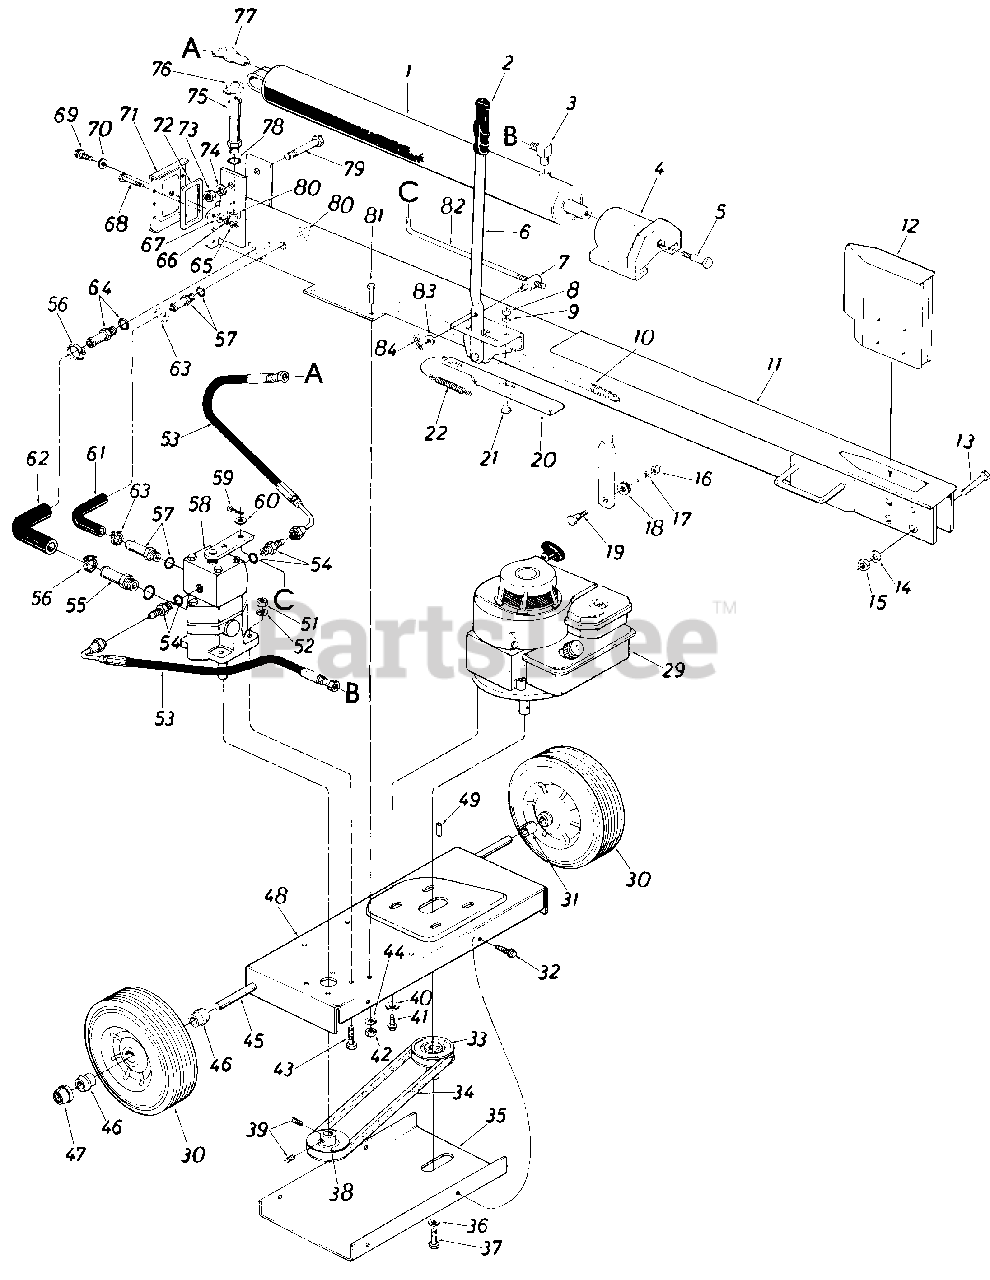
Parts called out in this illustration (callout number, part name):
1	2-1/2" Cylinder Ass'y. Comp.
2	Grip
3	90ø Elbow Adapter
4	Pusher Plate
5	Shoulder Bolt 5/8" Dia. x.660" Lg. 1/2-13 Thd.
6	Engagement Handle
7	Adjustment Ferrule
8	Hex Nut 5/16-18 Thd.
9	L.-Wash. 5/16" I.D.
10	Strainer Tube Ass y.
11	Oil Tank Ass'y. Comp
12	Wedge Ass y.
13	Hex Bolt 5/8-18 x 3.50" Lg. (Grade 5)
14	L.-Wash. 5/8" I.D.
15	Hex Nut 5/8-18 Thd.
16	Hex Nut 3/8-16 Thd.
17	L.-Wash. 3/8" I.D.
18	Rubber Wash.
19	Shoulder Bolt .498x .340
20	Engagement Brkt.
21	Shoulder Bolt .437" Dia. x.180" Lg.
22	Extension Spring .50" O.D. x 4. 25" Lg.
29	Engine-B & S
30	Wheel Ass'y. Comp. 10.0" x 2.75
31	Sleev .532" I.D. x 875" O.D. x .90" Lg.
32	Hex Wash. Hd. Self Tap. Scr. 1/4-20 x .50" Lg.
33	1/2" V-Pulley 7/8" I.D. x 7/8" I.D. x 3-1/4" O.D.
34	"V"-Belt (4L) 1/2" V x 30" Lg.
35	Belt Cover
36	L.-Wash. 5/16" I.D.
37	Hex Bolt 3/8-24 x 1.0" Lg.
38	1/2 (4L) "V"-Pulley 5/8" I.D. x 3-1/2" O.D.
39	Set Scr. 1/4-28 x .25" Lg.
40	Bell.-Wash..40" I.D. x .88" 0. D.
41	Hex Wash. Hd. TT-Tap Scr. 3/8-1 6 x .87 " Lg.
42	Hex Nut 5/16-24 Thd.
43	Hex Bolt 5/16-18 x 1.00" Lg.
44	L.-Wash . 5/16 " I . D . " I
45	Axle Shaft 5/8"'Dia. x 25.5" Lg.
46	Flange Brg. w/Flats .631" I.D.
47	Push Cap 5/8" Dia. Rod
48	Frame-Engine
49	Sq. Key 3/16" x 3/16" x 1.50" Lg.
51	Hex Nut 5/16-18 Thd.
52	L.-Wash. 5/16 " I . D.
53	High Pressure Hose
54	Adapter-or Boss to MJIC 9/16-18 to 7/16-20
55	Adapter 3/4" Tubing to 3/4-16 M-Boss
56	Hose Clamp 5/8" I.D.
57	Adapter 1/2" Tube 9/16-18 or M-Boss
58	Valve Ass'y.
59	Cotter Pin 3/32" Dia. x .75" Lg.
60	F l .-Wash. 344" 1. D . x .62" O.D. x .063
61	Return Hose.50" I.D.
62	Suction Hose .75" I.D.
63	Hose Clamp 1/4" I.D.
64	Adapter 1.0" Tube 1-1/16-12 "O"-Ring
65	Hex Nut 5/16-18 Thd.
66	L.-Wash. 5/16" I.D.
67	Fl.-Wash. .343" I.D. x .687" O.D. x .062
68	Hex Bolt 5/16-18 x 1.50" Lg.
69	Hex Hd. Tap Scr. 5/16"
70	Gasket
71	End Plate
72	Gasket
73	Hex Nut 3/4" Thd.
74	L.-Wash. 3/4" I.D.
75	Filler Tube Ass'y.
76	Oil Fill Cap
77	45ø M ale Adapter 7/16-20 MJ-1/4-18 NP
78	"O"-Ring .92" I.D. x 1.16" O.D. x .116 Dia.
79	Hex Bolt 3/4" x 4.0" Lg.
80	Hex Nut 11/16-12 Thd.
81	Hex Bolt 5/16-24 x 1 .00" Lg. (Grade 5)
82	Engagement Rod 16.75" Lg.
83	Fl.-Wash. .344" I.D. x.62" O.D. x .063
84	HairPin Cotter 5/16" Dia.
